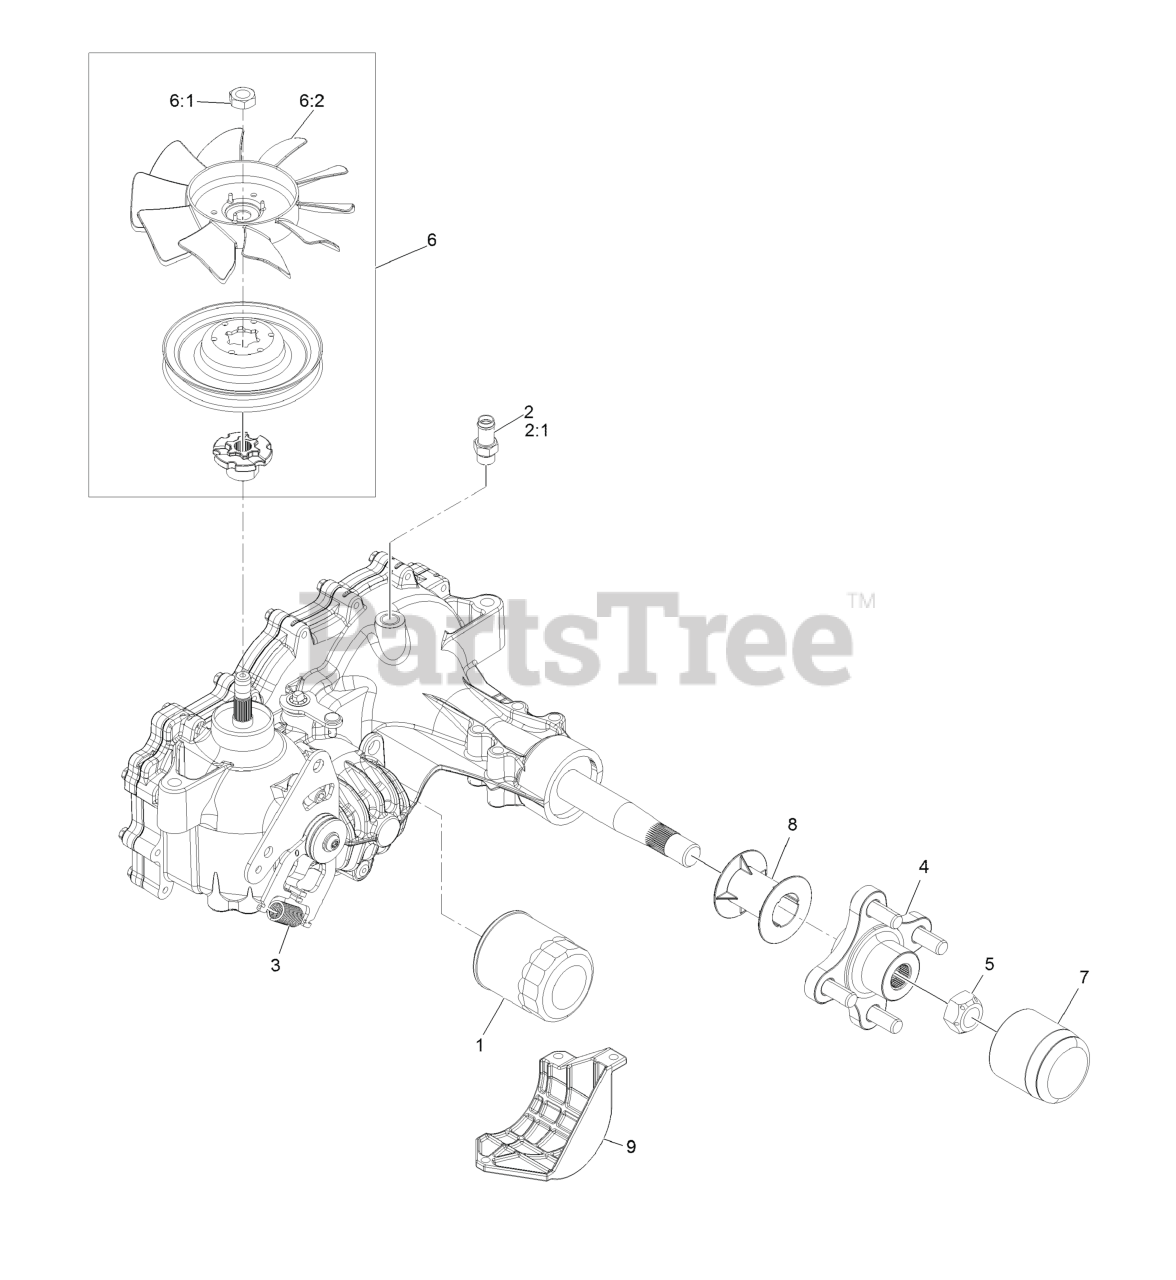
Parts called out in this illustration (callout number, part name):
1	ELEMENT-OIL FILTER, HYD
2	ADAPTER-STRAIGHT
2:1	O-RING
3	SPRING-EXTENSION
4	HUB-OFFSET
5	NUT-HUB
6	Fan And Pulley Kit
7	CAP-AXLE, LONG
8	TUBE-AXLE
9	GUARD-FILTER, LH
